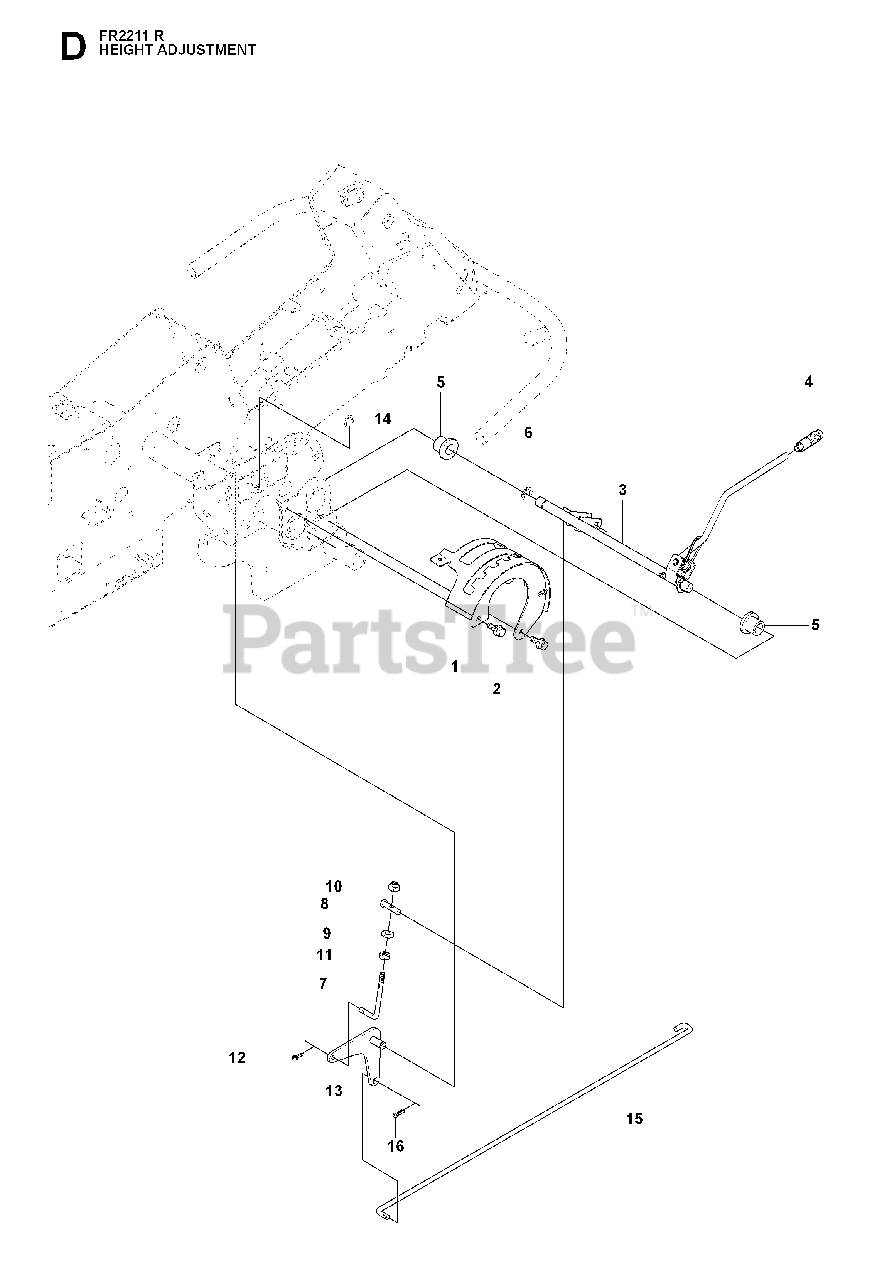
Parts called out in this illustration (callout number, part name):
4	GEAR STICK KNOB
5	BUSHING
9	WASHER
10	LOCKNUT M8
11	NUT
12	SPLIT PIN
14	RETAINING RING
16	SPLIT PIN
